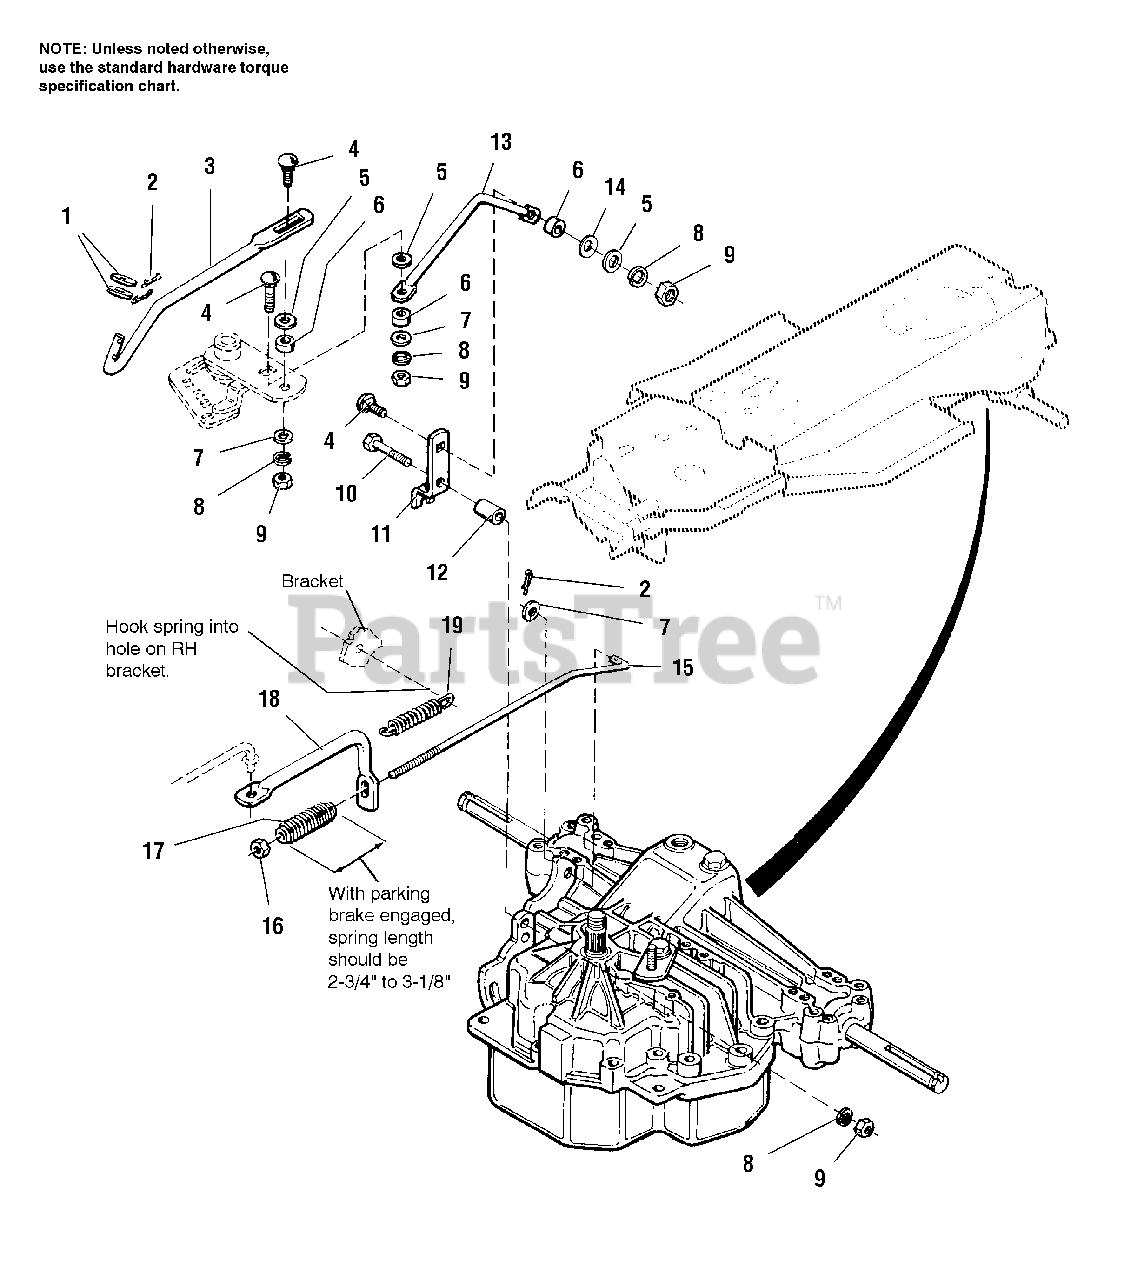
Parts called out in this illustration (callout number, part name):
1	WASHER, 17/32 x 1-1/4 x 5/64
2	COTTER PIN
3	ROD, Shift, Front
4	CARRIAGE BOLT, 5/16-18 x 1-1/4
5	WASHER, 11/32 x 1 x 1/8
7	WASHER, Plain, 5/16
8	LOCKWASHER, 5/16
9	NUT, Hex, Full, 5/16-18
10	CAPSCREW, Hex, 5/16-18 x 1-3/4
11	LEVER, Control
13	ROD, Shift, Rear
14	WASHER, Curved
16	NUT, Hex, Nylon Lock, 5/16-18
19	SPRING, Brake Arm
